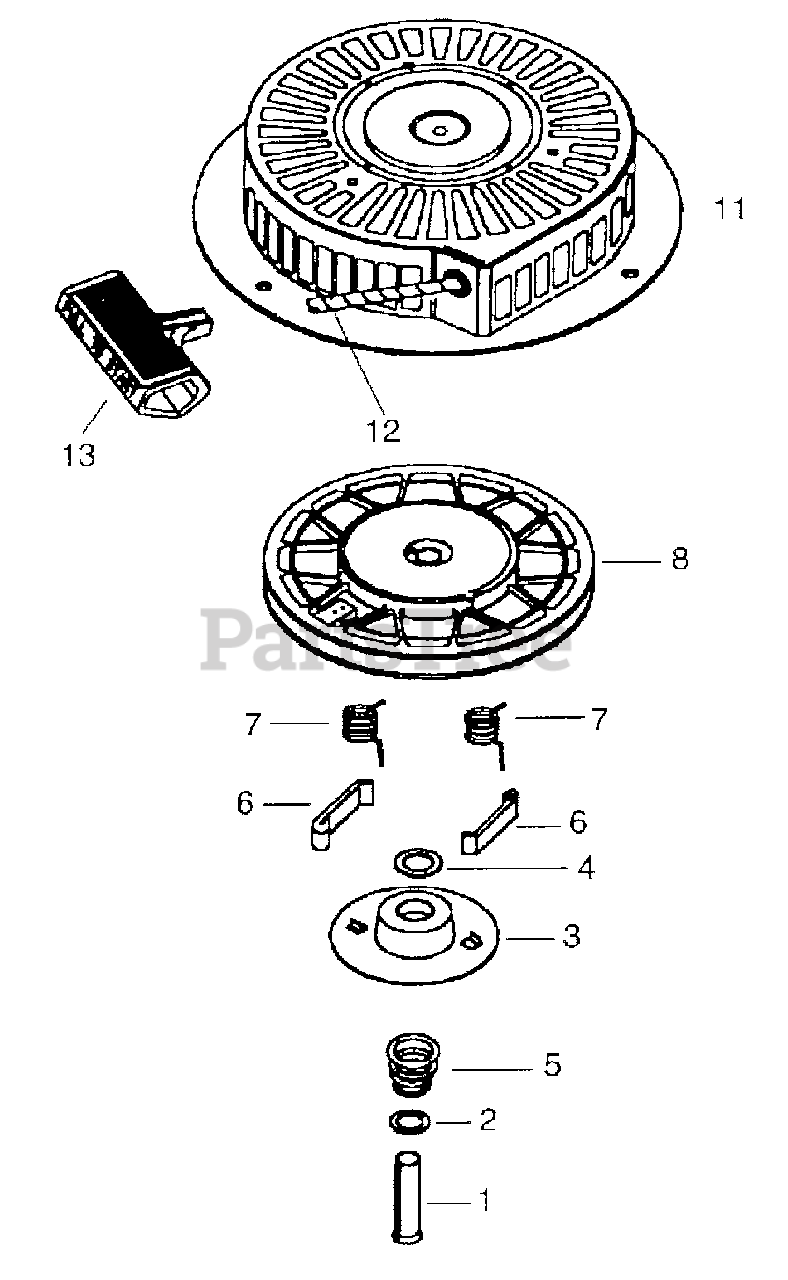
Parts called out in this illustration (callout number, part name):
1	Spring Pin
5	Brake Spring
6	Starter Dog
7	Dog Spring
8	Pulley & Rewind Spring Assy
11	Starter Housing Assy
12	Starter Rope
13	Starter Handle
